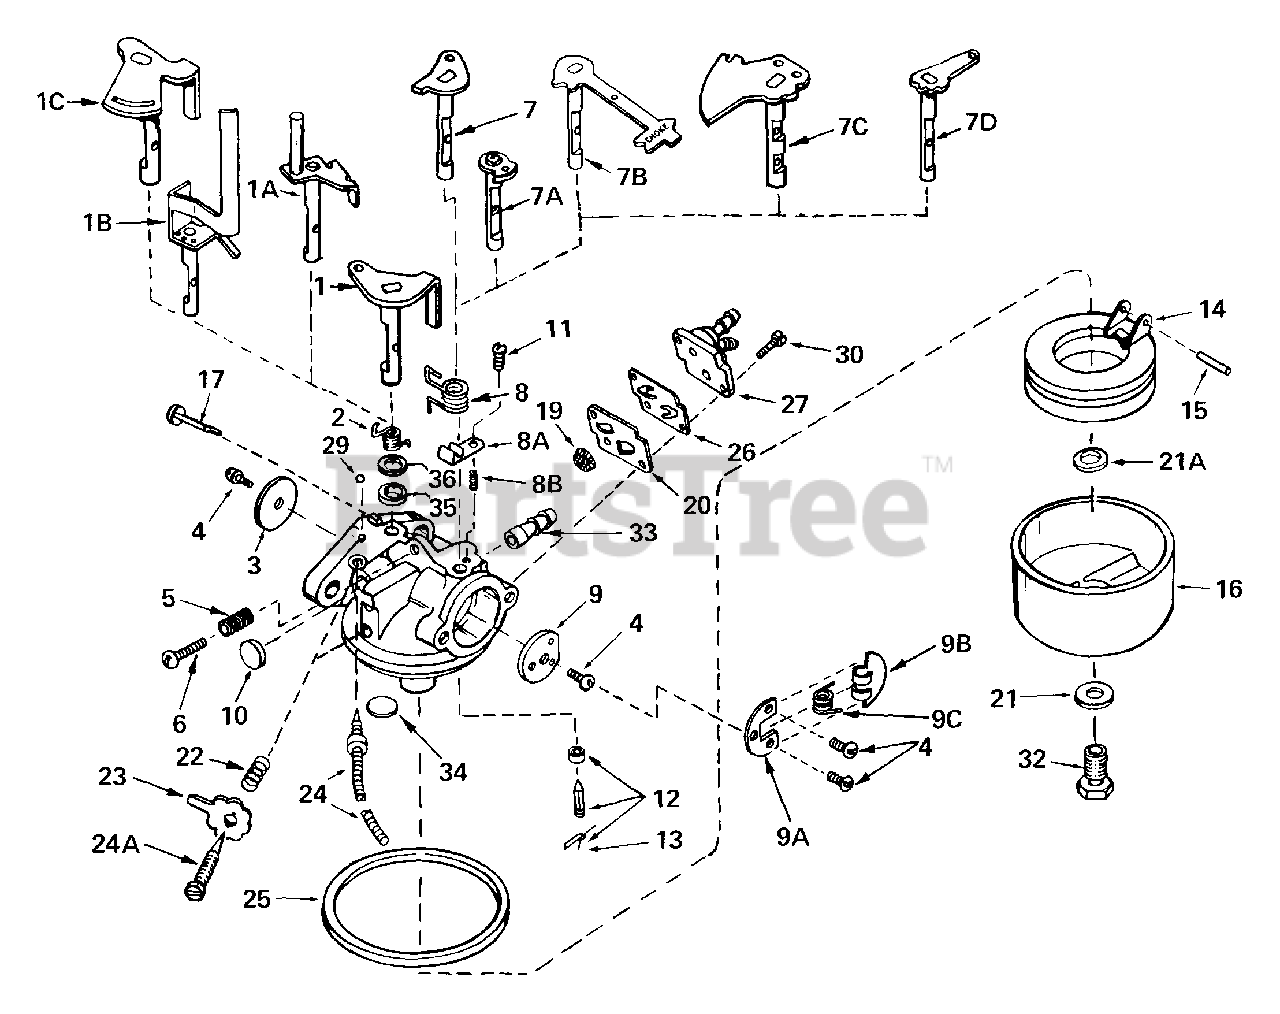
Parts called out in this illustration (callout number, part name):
1A	"Shaft & Lever Assy., Throttle
2	Spring, Throttle return
3	Shutter, Throttle
4	Screw, Throttle & Choke shutter
7A	Shaft & Lever Assy., Choke
8A	Spring, Detent
9	Shutter, Choke
10	Plug, Welch
11	Screw, Detent spring
12	Inlet Needle, Seat & Clip Assy.
13	Clip, Inlet needle
14	Float, Carburetor
15	Shaft, Float
16	Bowl, Float
17	Element, Pump
19	Screen, Filter
20	Gasket
21	Gasket, Bowl-to-body
24	Screw, Idle adj.
25	Gasket, Bowl-to-body
26	Valve, Flap
27	Cover Assy., Valve
32	Nut, Float bowl
